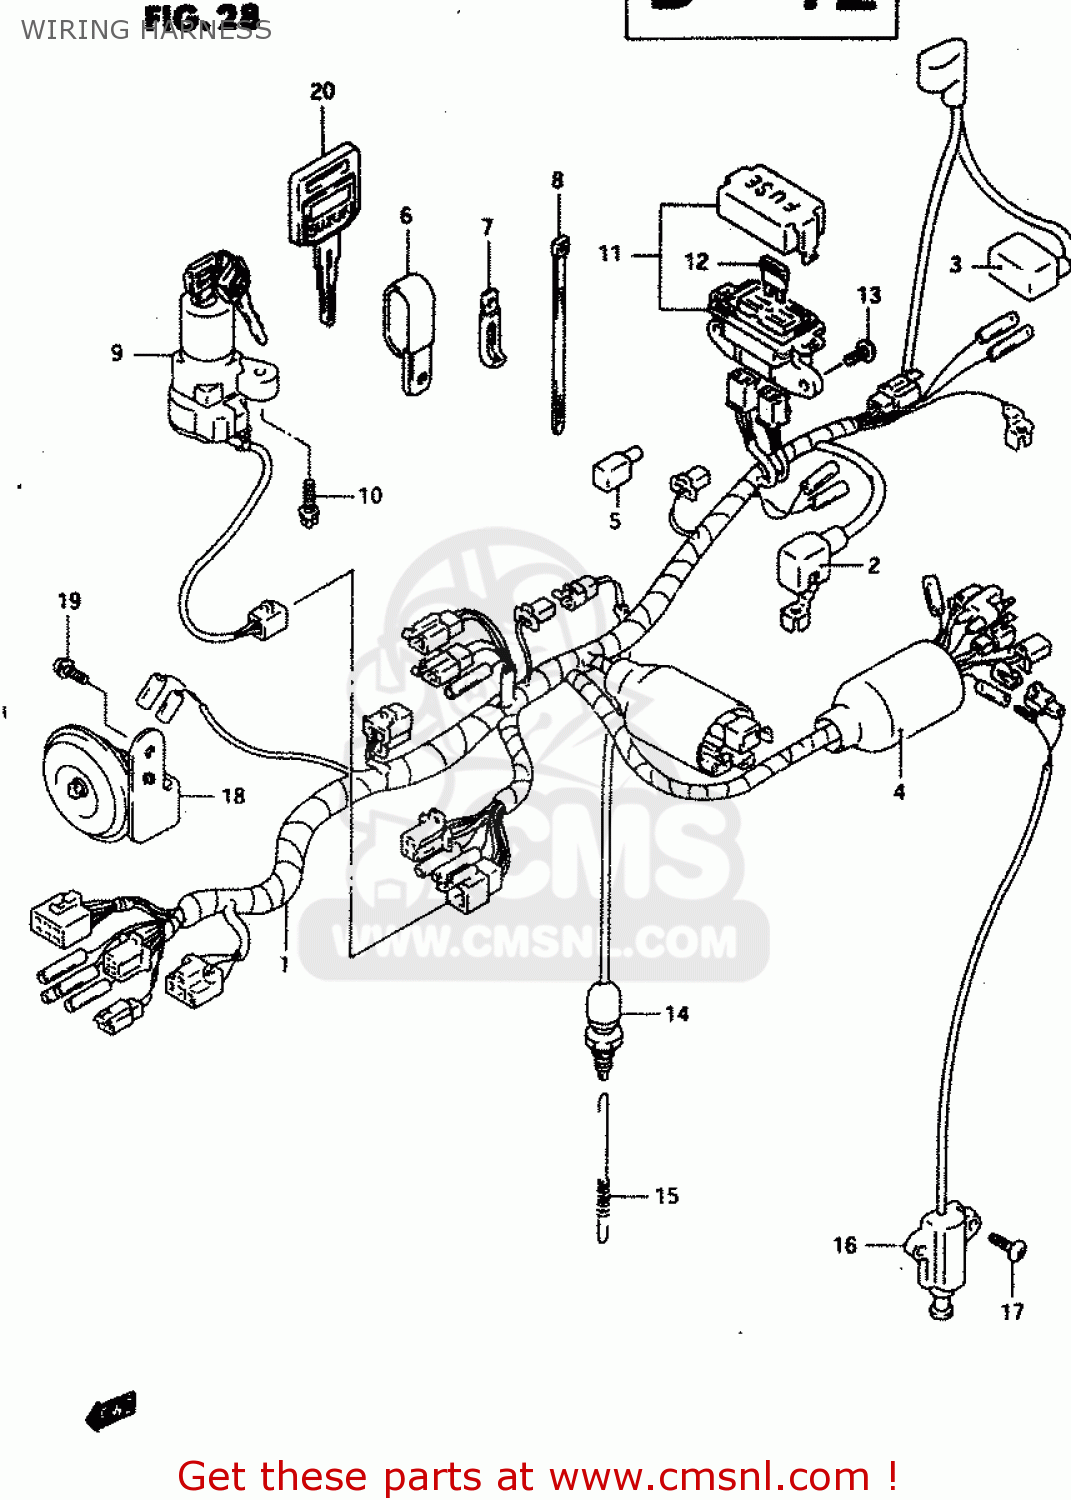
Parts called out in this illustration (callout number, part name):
1	HARNESS,WIRING
2	CAP,BATTERY PLUS
3	CAP,STARTER RELAY
4	BOOT,WIRING HARNESS
5	COVER,DECOMPRESSION CONTROL UNIT
6	CLAMP
7	CLAMP(L:45)
8	CLAMP L:165
9	LOCK ASSY,STEERING
10	SCREW(6X18)
11	BOX ASSEMBLY,FUSE
12	FUSE(10A)
13	SCREW 6X12
14	SWITCH ASSY,STOP LAMP
15	SPRING
16	SWITCH ASSY,SIDE STAND
17	SCREW, 6X20
18	HORN ASSY
19	BOLT
20	KEY,BLANK
